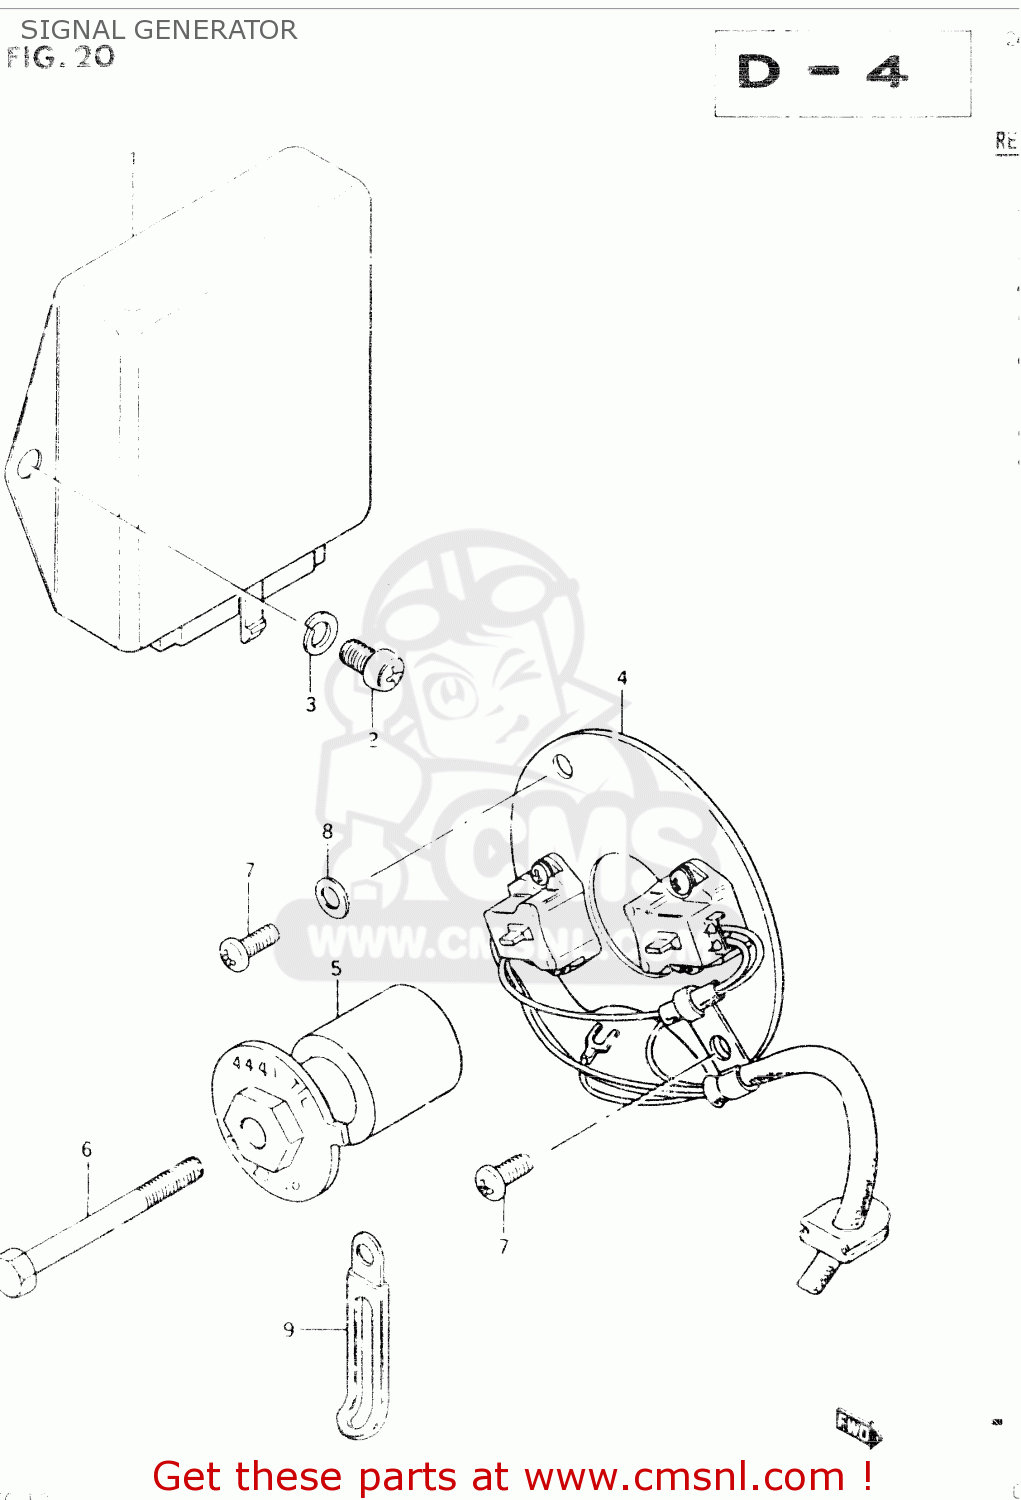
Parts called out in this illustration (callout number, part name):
1	IGNITER UNIT A
2	SCREW
3	WASHER,LOCK
4	SIGNAL GENERATOR ASSY
5	ROTOR, SIGNAL
6	BOLT 6X60
7	SCREW(5X12)
8	WASHER(5.5X10X0.8)
9	CLAMP L:35
